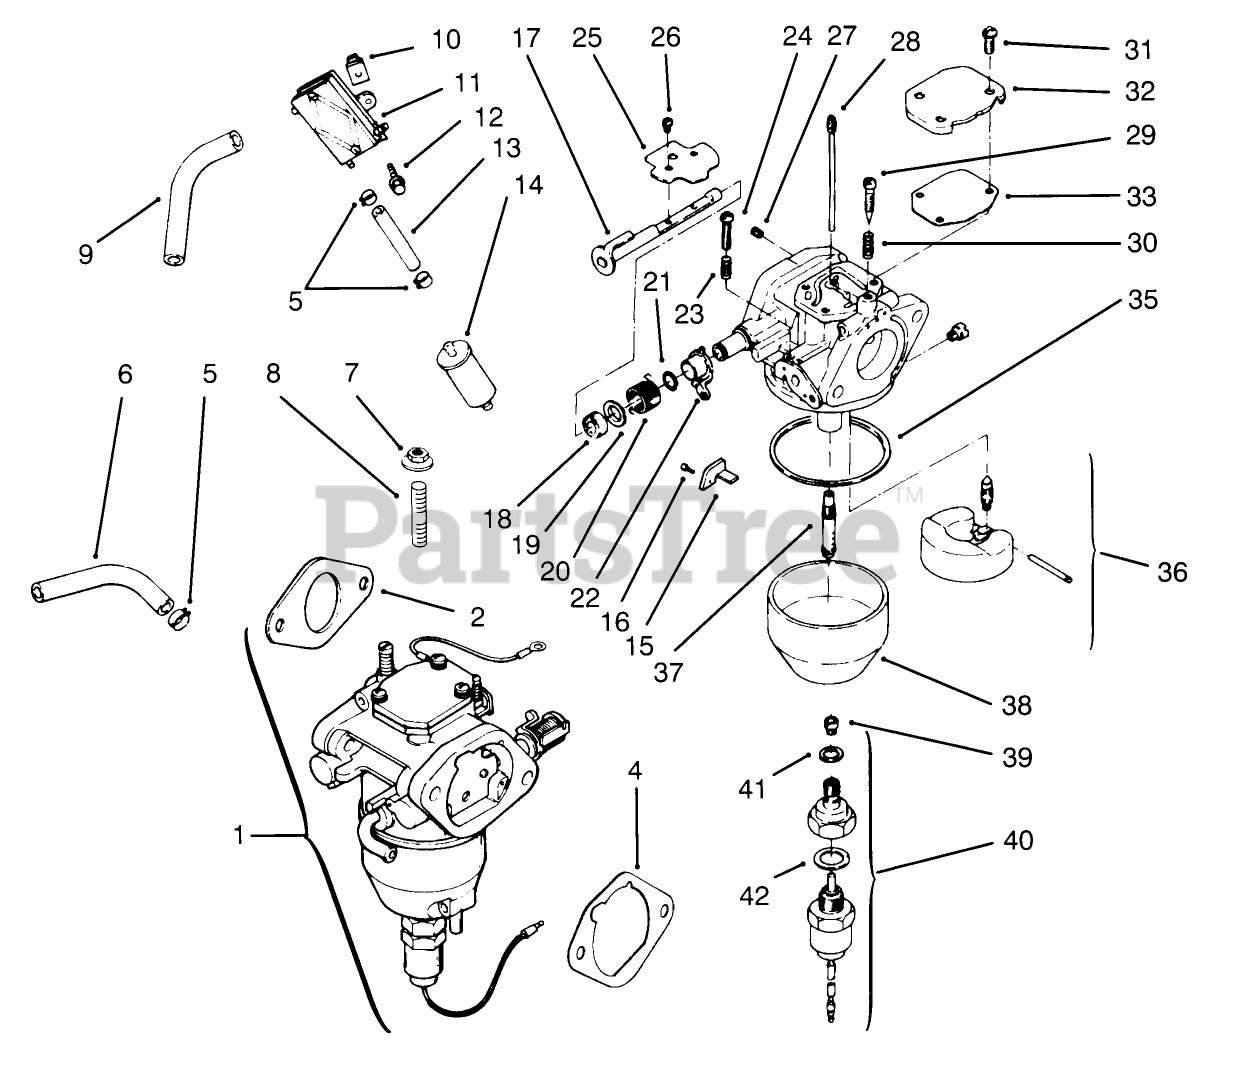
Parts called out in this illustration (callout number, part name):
1	Kit-Carb INCL 2/4/15-42 (Only On: 72103)
2	Gasket-Carburetor (Only On: 72103)
4	Gasket-A/C Base (Only On: 72103, 72083)
5	Clamp
6	Line-Fuel 10 1/2" (Only On: 72103, 72083)
8	Stud M6x1.0x95 (Only On: 72103, 72083)
9	Line-Fuel 12" (Only On: 72103)
11	Pump-Fuel
13	Line-Fuel 3 1/2" (Only On: 72103)
14	Filter-Fuel (Only On: 72042,72043,72062,72063)
15	Bracket-Throttle Stop (Only On: 72103, 72083)
16	Screw M2.5X45X5.5 (Only On: 72103)
17	Shaft-Choke (Only On: 72103, 72083)
18	Washer (Only On: 72103, 72083)
19	Collar-Choke (Only On: 72103, 72083)
20	Spring-Choke Return (Only On: 72103, 72083)
21	Ring-Choke Lever (Only On: 72103)
22	Lever-Choke (Only On: 72103)
23	Spring-Throttle Screw (Only On: 72103, 72083)
24	Screw-Throttle Adjust (Only On: 72103, 72083)
25	Valve-Choke (Only On: 72103)
26	Screw-Throttle Shaft (Only On: 72103, 72083)
27	Jet-Air Bleed (Only On: 72103)
28	Jet-Slow (Only On: 72103)
29	Screw-Idle Adjust (Only On: 72103, 72083)
30	Spring-Idle Adjust Screw (Only On: 72103)
31	Screw (Only On: 72103)
32	Cover-Passage (Only On: 72103, 72083)
33	Gasket-Passage Cover (Only On: 72103, 72083)
35	Gasket-Float Chamber (Only On: 72103)
36	Kit-Float Repair (Only On: 72103)
37	Nozzle-Main (Only On: 72103,72083)
38	Chamber-Float (Only On: 72103)
39	Jet-Main (Only On: 72103)
40	Kit-Solenoid INC 41-42 (Only On: 72103, 72083)
41	Gasket-Chamber Screw (Only On: 72103)
42	Gasket-Solenoid (Only On: 72103, 72083)
